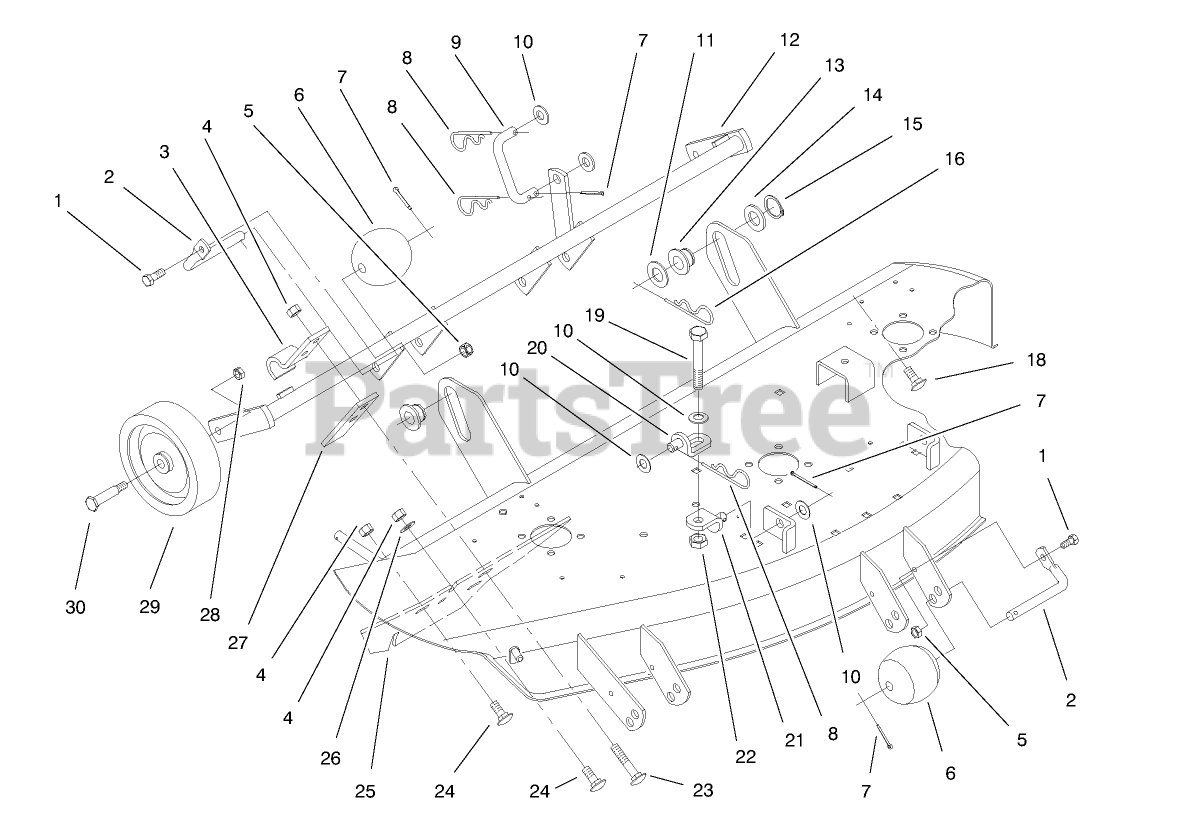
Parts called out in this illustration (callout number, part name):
1	SCREW-HH
4	NUT-LOCK, NI
5	NUT-LOCK, NI
6	ROLLER
7	PIN-COTTER
8	PIN-COTTER, HAIR
9	LINK-REAR
10	WASHER-FLAT
11	WASHER-FLAT
13	ROLLER-LIFT
14	WASHER-FLAT
15	RING-RETAINING
16	PIN-HAIR
18	SCREW-CARR
19	SCREW-HH
20	BRACKET-LIFT, LOWER
21	BRACKET-LIFT, UPPER
22	NUT-JAM
23	SCREW-CARR
24	SCREW-CARR
26	WASHER-FLAT
29	WHEEL
30	BOLT-SHOULDER
